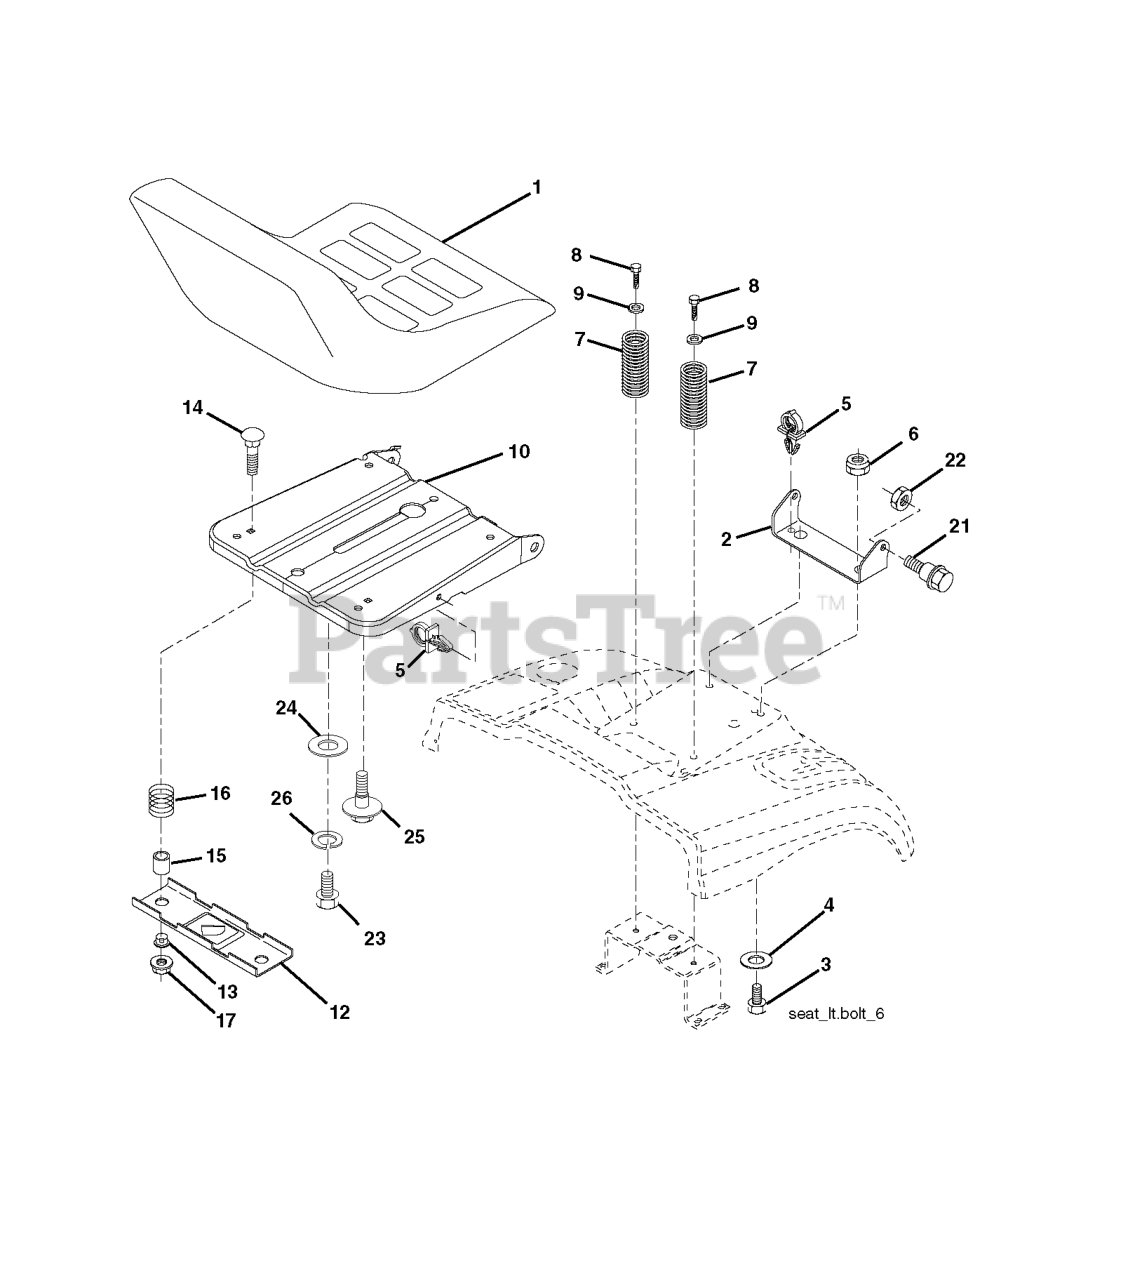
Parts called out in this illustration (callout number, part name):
1	SEAT.XG090.BLK.KB/BLT.NO-LOG
2	SEAT PIVOT BRKT
3	BOLT, HEX 3/8-16X1
6	NUT
7	SPRING COMPRESSION
8	SCREW 3/8-16X1
9	WASHER
10	PAN.ASM.SEAT.1SLOT
12	BRKT.MNTNG.SWITCH.SEAT.BLACK
14	BOLT.ROUND.HEAD.SQUARE.NECK
15	SPACER SPLIT 28X.96
17	NUT T
21	BOLT.SHOULDER.5/16-18
22	NUT.71038.31-18.HEX.NYLOCK
23	BOLT.HEX.BLACK
25	BOLT,SHOULD
26	LOCKWASHER
